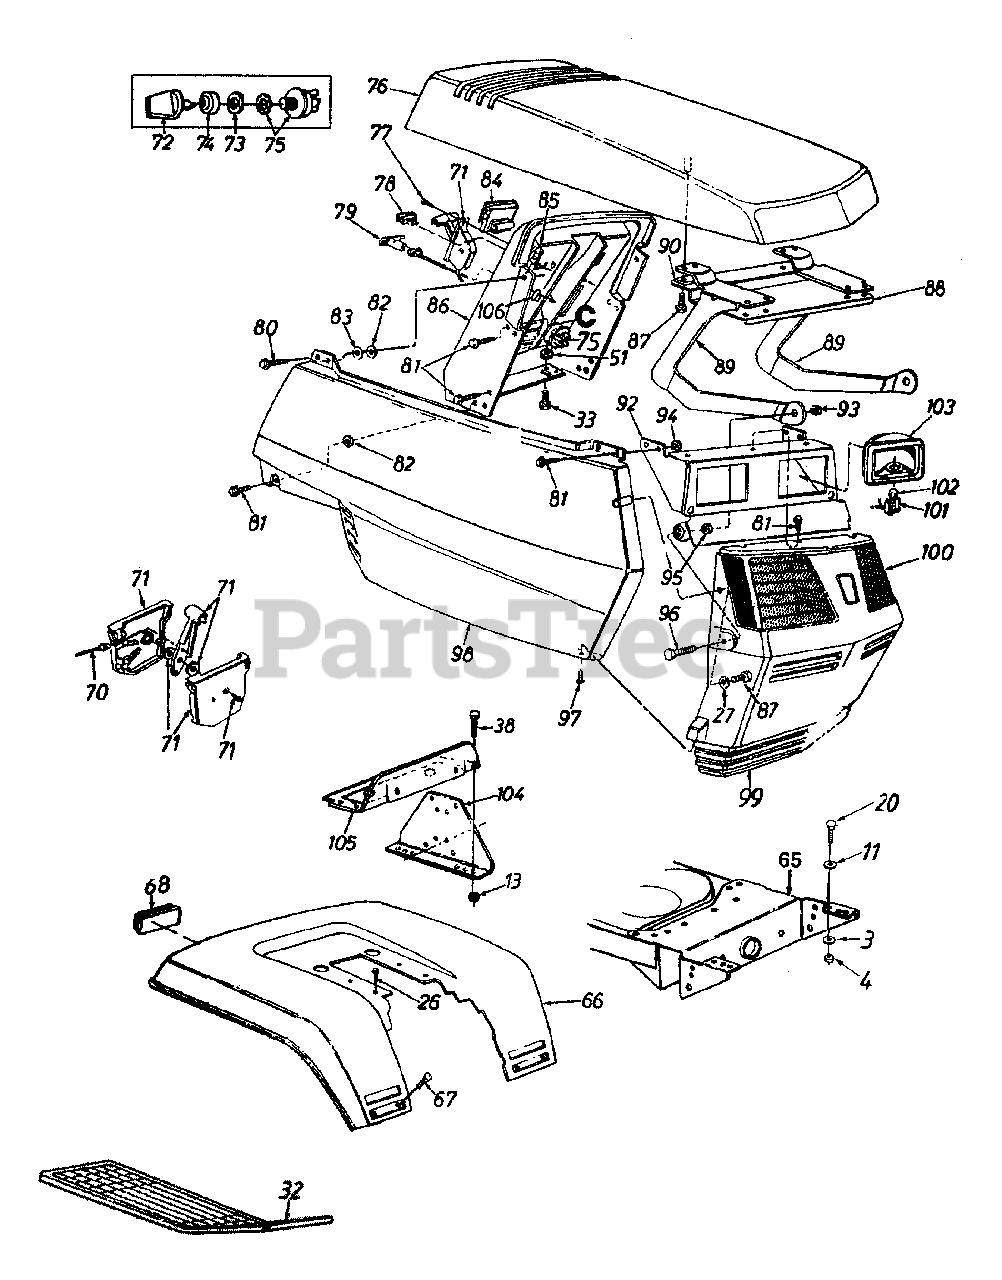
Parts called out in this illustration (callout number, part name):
11	Lock Washer 5/16" I.D.
13	Hex Sems Nut 1/4-20 Thd.
26	Hex Wash. Hd. AB-Tap Scr. 5/16 x .75"
27	Flat Washer .218" I.D. x .5" O.D.
32	Rubber Foot Pad-LH
33	Hex Bolt 5/16-18 x .75" Lg.
38	Hex Bolt 1/4-20 x .62" Lg.
51	Hex Sems Nut 5/16-18 Thd.
70	Throttle Wire 18.5" Lg.
71	Throttle Control Box Assembly
72	Ignition Key
73	Ignition Switch Nut
74	Ignition Switch Cap
75	Ignition Switch
76	Hood - Red
77	Truss Mach. AB-Tap Scr. #10 x.5" Lg.
78	Light Switch
79	Choke Control 29" Lg.
80	Hex Wash. Hd. Tap Scr. 1/4 x .75" Lg.
81	Hex Tap Scr. 1/4-20 x .5" Lg.
82	Push Nut Fastener
83	Flat Washer .27" I.D. x .948"
84	Ammeter
85	Speed Nut 1/4-20 Thd.
86	Dash Panel
87	Hex Wash. Hd. B-Tap Scr. 1/4 x .75" Lg.
94	Hex Lock Nut 1/4-20 Thd.
95	Hex Jam Nut 5/16-18 Thd.
96	Hex Bolt 5/16-18 x 7/8" Lg.
97	Truss Mach. B-Tap Scr. #10 x .5" Lg.
98	Side Cover-RH - Red
99	Grille- Red
100	Lens-LH
101	Twist Lock-Lamp Socket
102	Lamp
103	Headlight Housing
